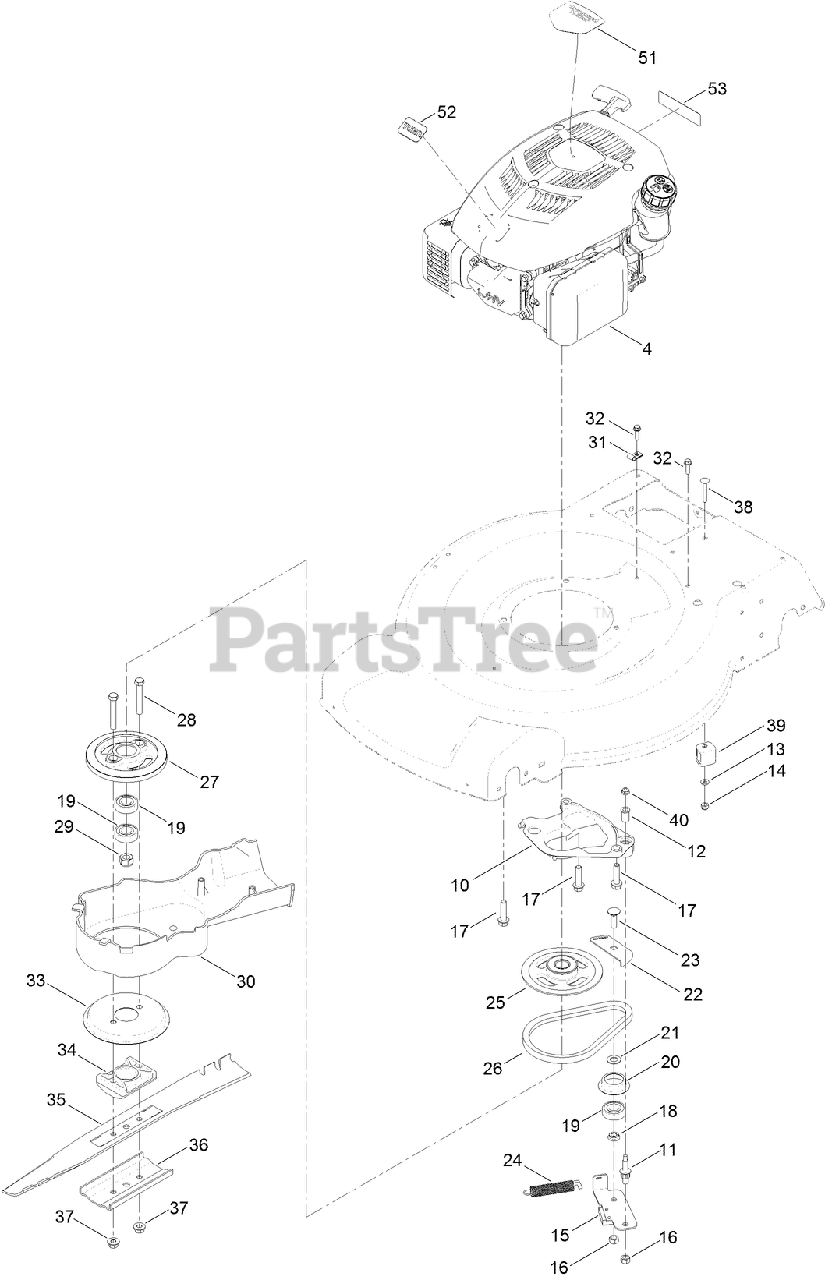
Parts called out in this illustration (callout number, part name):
4	ENGINE-1P65F-2
10	PLATE-ANCHOR
11	BOLT-SHOULDER
12	BUSHING
13	WASHER-FLAT
14	NUT-LOCK, NI
15	PLATE-BRAKE
16	NUT-HEX
17	SCREW-HWH
18	SPACER-BEARING
19	BEARING-BALL
20	RETAINER-BELT
21	SPACER
22	PLATE-GUIDE
23	BOLT-CARR
24	SPRING-TENSION, BRAKE
25	PULLEY
26	BELT
28	SCREW-HH
29	NUT-HEX
31	CLIP-CLOSED, INSULATED
32	SCREW-HWH
33	DISC
34	SUPPORT-BLADE
35	BLADE-22 INCH
36	SUPPORT-BLADE
37	NUT-FLANGE, LOCK
38	SCREW-CARR
39	ANCHOR-CABLE
40	NUT-HF
51	DECAL-SHROUD
53	DECAL-ARRESTER, SPARK
